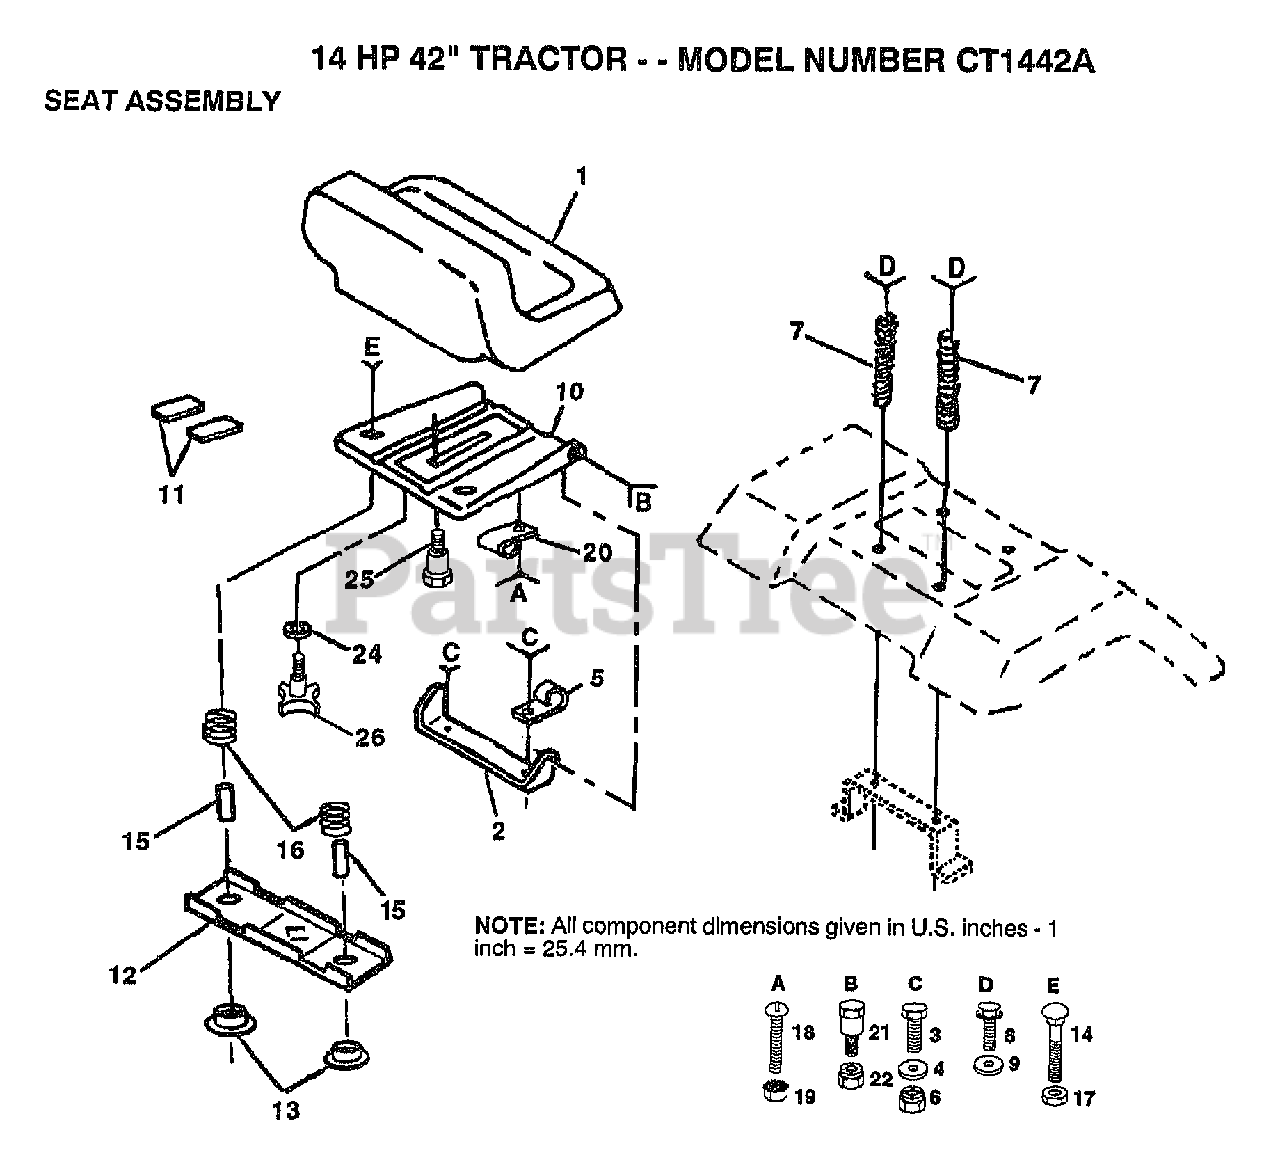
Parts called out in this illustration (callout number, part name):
4	WASHER PM
5	CLIP T
7	SPRING COMPRESSIO
8	SCREW GTV
9	WASHER
11	STRIP FORM
12	BRKT SWITCH
13	BUSHING
15	SPACER SPLIT
16	SPRING COMPRESSED
19	"NUT,KEPS"
24	WASHER
25	"BOLT,SHOULDER"
26	"KNOB 1/2"" YT"
